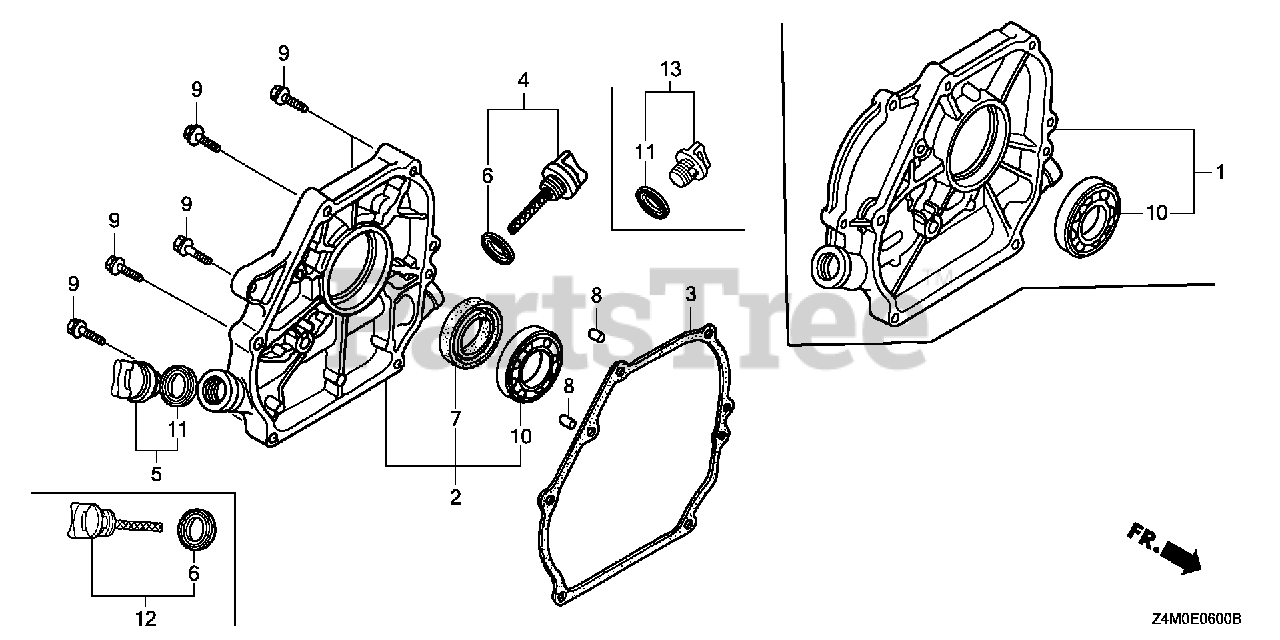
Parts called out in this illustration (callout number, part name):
2	COVER ASSY., CRANKCASE
3	GASKET, CASE COVER (NON-ASBESTOS)
4	CAP ASSY., OIL FILLER
5	CAP ASSY., OIL FILLER
6	GASKET, OIL FILLER CAP
7	OIL SEAL (25X41X6)
8	PIN A, DOWEL (8X14)
9	BOLT, FLANGE (8X32)
10	BEARING, RADIAL BALL (6205)
11	GASKET, OIL FILLER CAP
